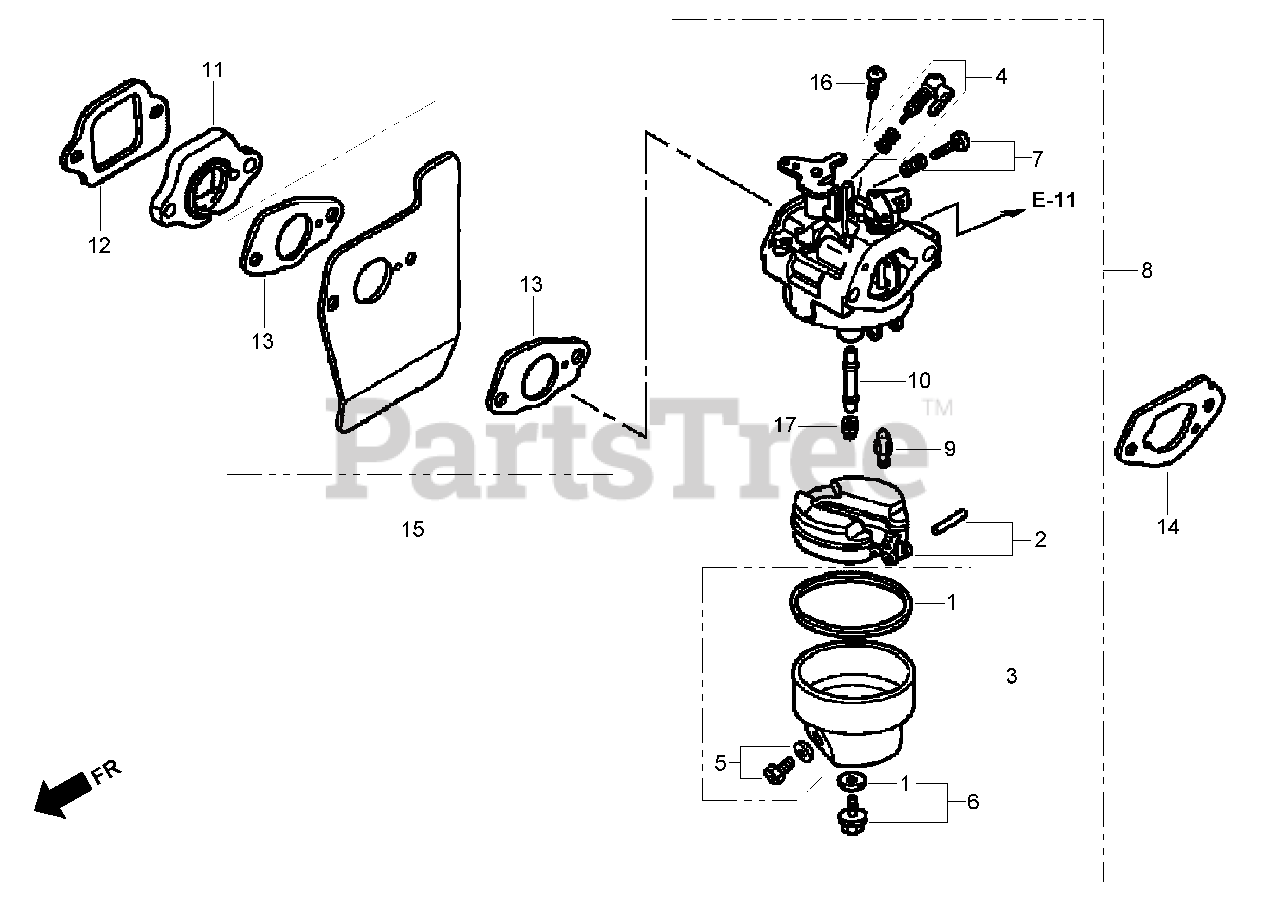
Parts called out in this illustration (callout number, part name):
1	GASKET SET
2	FLOAT SET
3	FLOAT CHAMBER SET
4	SCREW SET
5	DRAIN SCREW SET
6	SCREW SET
7	SCREW SET (THROTTLE STOP)
8	CARBURETOR ASM (BB65G A)
9	VALVE-FLOAT
10	NOZZLE-MAIN
11	INSULATOR-CARBURETOR
12	GASKET-INSULATOR
13	GASKET-CARBURETOR
14	GASKET-CARBURETOR
15	GUIDE-AIR
16	SCREW-PAN (5X6)
17	JET-MAIN (No.62)
17	JET-MAIN (No.65)
17	JET-MAIN (No.68)
